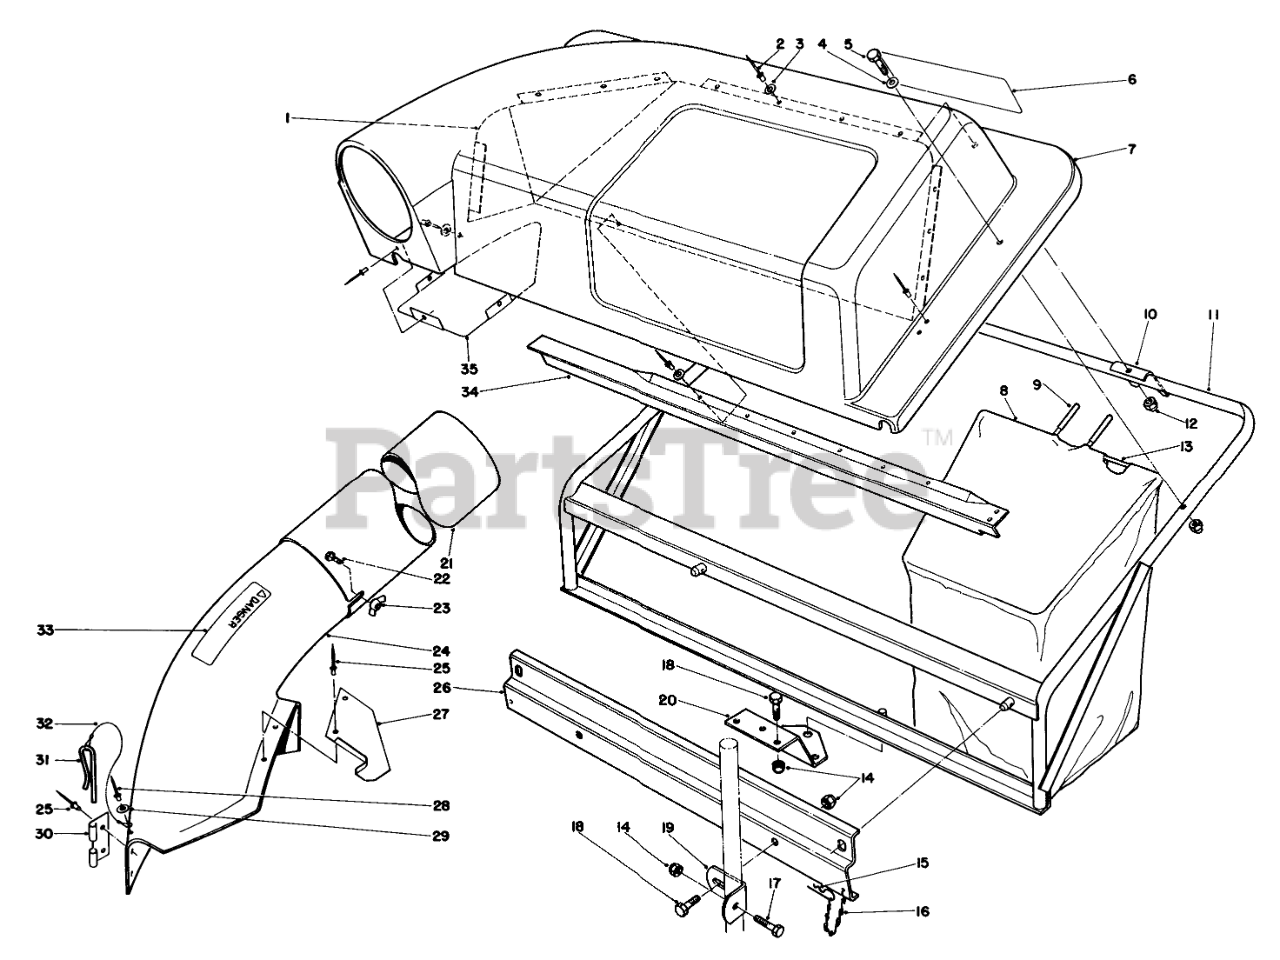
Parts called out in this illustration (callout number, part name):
1	Screen Cover
3	WASHER-FLAT
4	WASHER-PLAIN
5	SCREW-HH
6	TWIN BAGGER DECAL
7	Cover
9	GRIP-HANDLE, BAG
10	BAG FRAME BRKT
11	NUT-LOCK, CAP
12	Frame
13	Frame-Bag
14	NUT-LOCK, CONE
15	PIN-HAIR
16	6-LINK CHAIN W/HOOK
17	SCREW-HH
18	SCREW-HH
19	Bracket Mtg. Grass Catcher
20	Plate-Mtg. Grass Catcher
21	TUBE(ROUND&LONG)
22	BOLT-CARR
23	NUT-WING SPECL
24	Chute Assembly (Incl. Ref. #25, 27-33)
25	RIVET-BLIND
26	Bracket Frame Support
27	CHUTE SUPT BRKT
28	RIVET-BLIND
29	WASHER-PLAIN
30	BRACKET-MOUNTING, CHUTE
31	PIN-LOCKING, CHUTE
32	LANYARD
33	Decal-Chute
34	SCREEN SUPT BRKT B
35	Shield Cover
